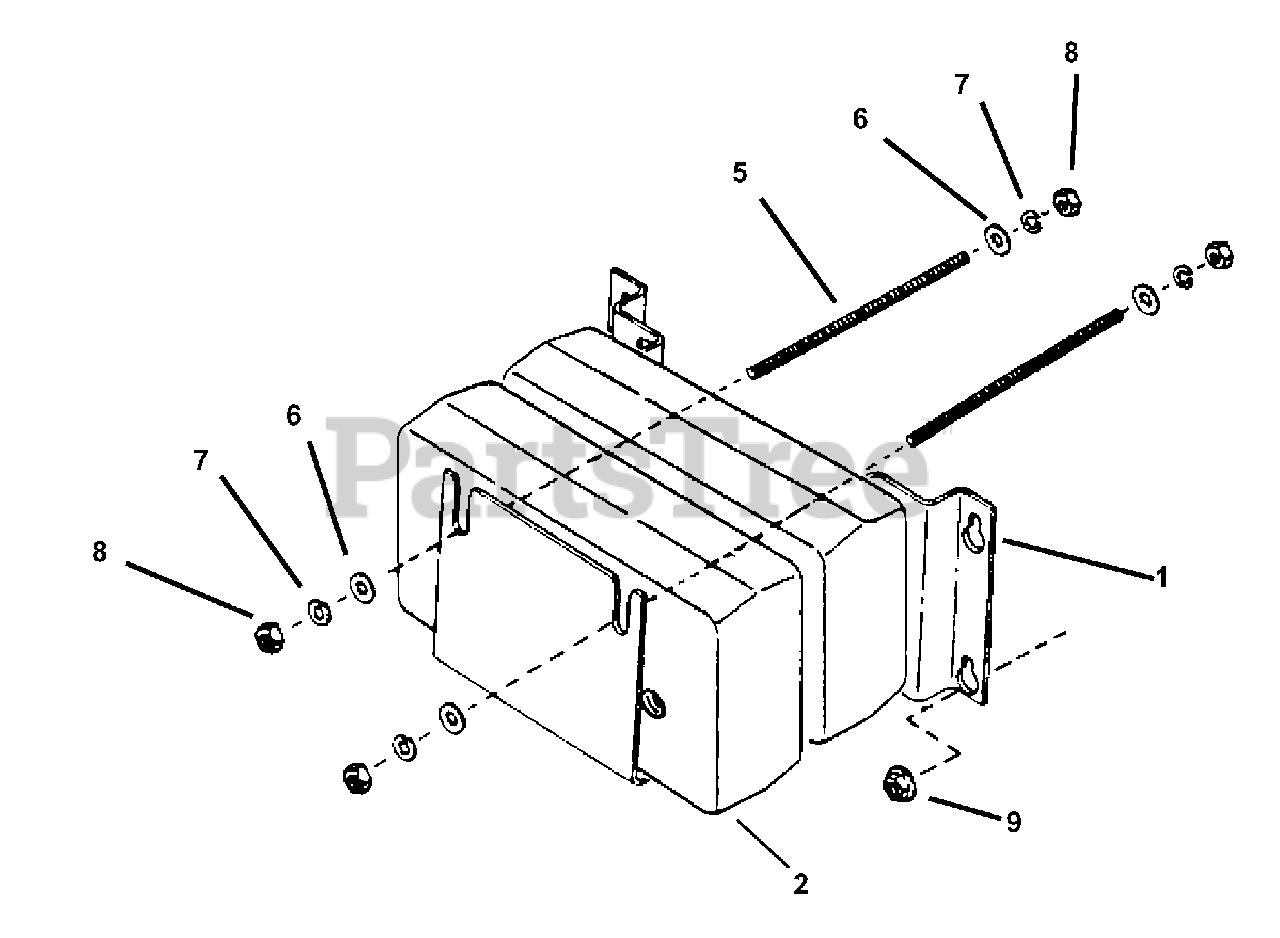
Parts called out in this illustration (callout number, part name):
1	BRACKET, Weight Holder
2	WEIGHT, 38 LB.
5	ROD, 3/8-16 x 9" Threaded
6	WASHER, 3/8" Flat
7	WASHER, 3/8 Split Lock
8	NUT, 3/8-16 Hex, Grade B or 5
9	NUT, 5/16-18 Hex Flange Lock, Grade 5
